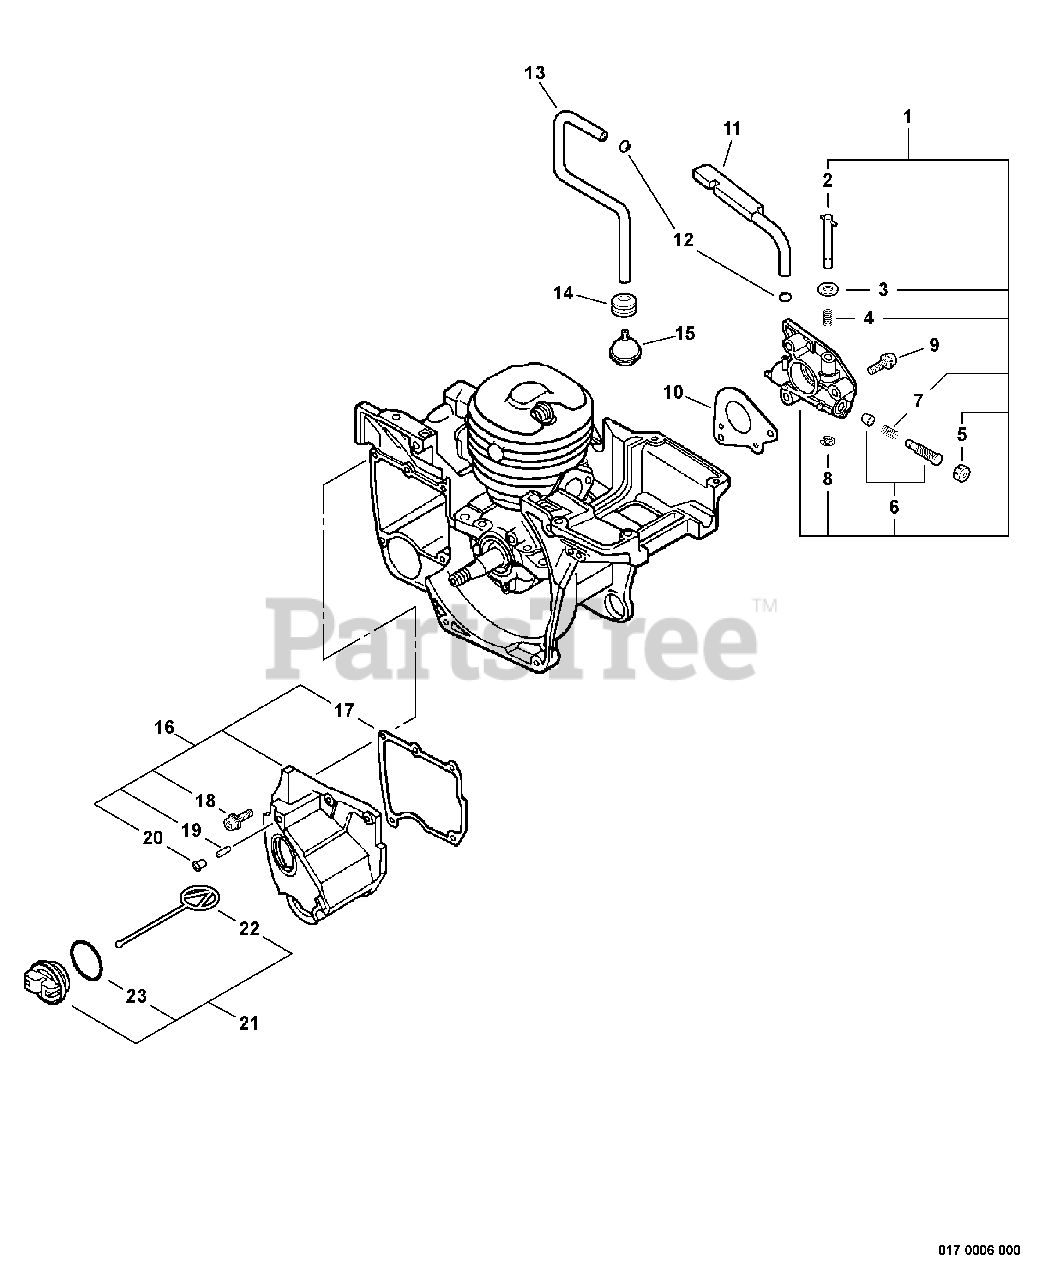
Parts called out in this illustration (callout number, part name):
1	AUTO-OILER ASSY
2	NEEDLE, ADJUST
5	CAP, OIL PUMP
6	PLUNGER ASSY
7	SPRING, PLUNGER
8	RING, RETAINING
9	SCREW - 4X16
10	SEAL, DUST
11	PIPE - OIL
12	CLIP - 6.5
13	PIPE - OIL
15	FILTER, OIL
16	OIL TANK ASSY
17	GASKET, OIL TANK
18	SCREW - 4X16
19	VENT, TANK
21	CAP ASSY - ORANGE
22	CONNECTOR, CAP
23	O-RING - 25
